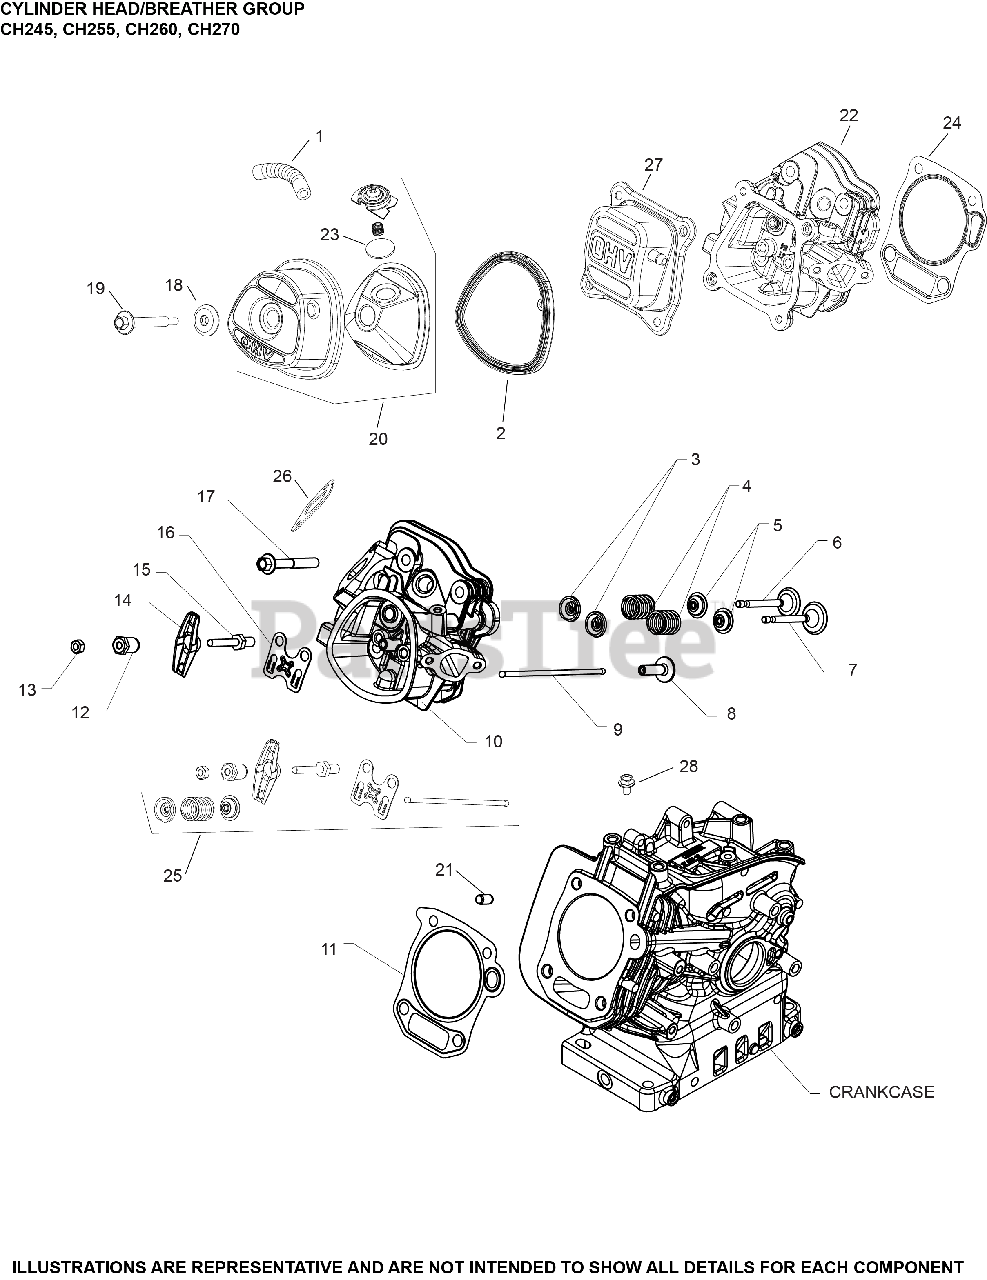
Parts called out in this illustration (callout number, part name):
1	TUBE, BREATHER
3	RETAINER, VALVE SPRING
4	SPRING, VALVE
5	SEAL, VALVE
6	VALVE, EXHAUST
7	VALVE, INTAKE
9	ROD, PUSH
12	PIVOT, ROCKER ARM
13	NUT, HEX JAM
14	ARM, ROCKER
15	STUD, ROCKER ARM - (#1407222S)
16	PLATE, PUSHROD GUIDE
17	SCREW, HEX FLANGE CYL HEAD
22	CYLINDER HEAD
23	REED, BREATHER
24	GASKET, CYLINDER HEAD
25	KIT, VALVE TRAIN
26	GASKET, MUFFLER
27	COVER, VALVE ASSEMBLY
